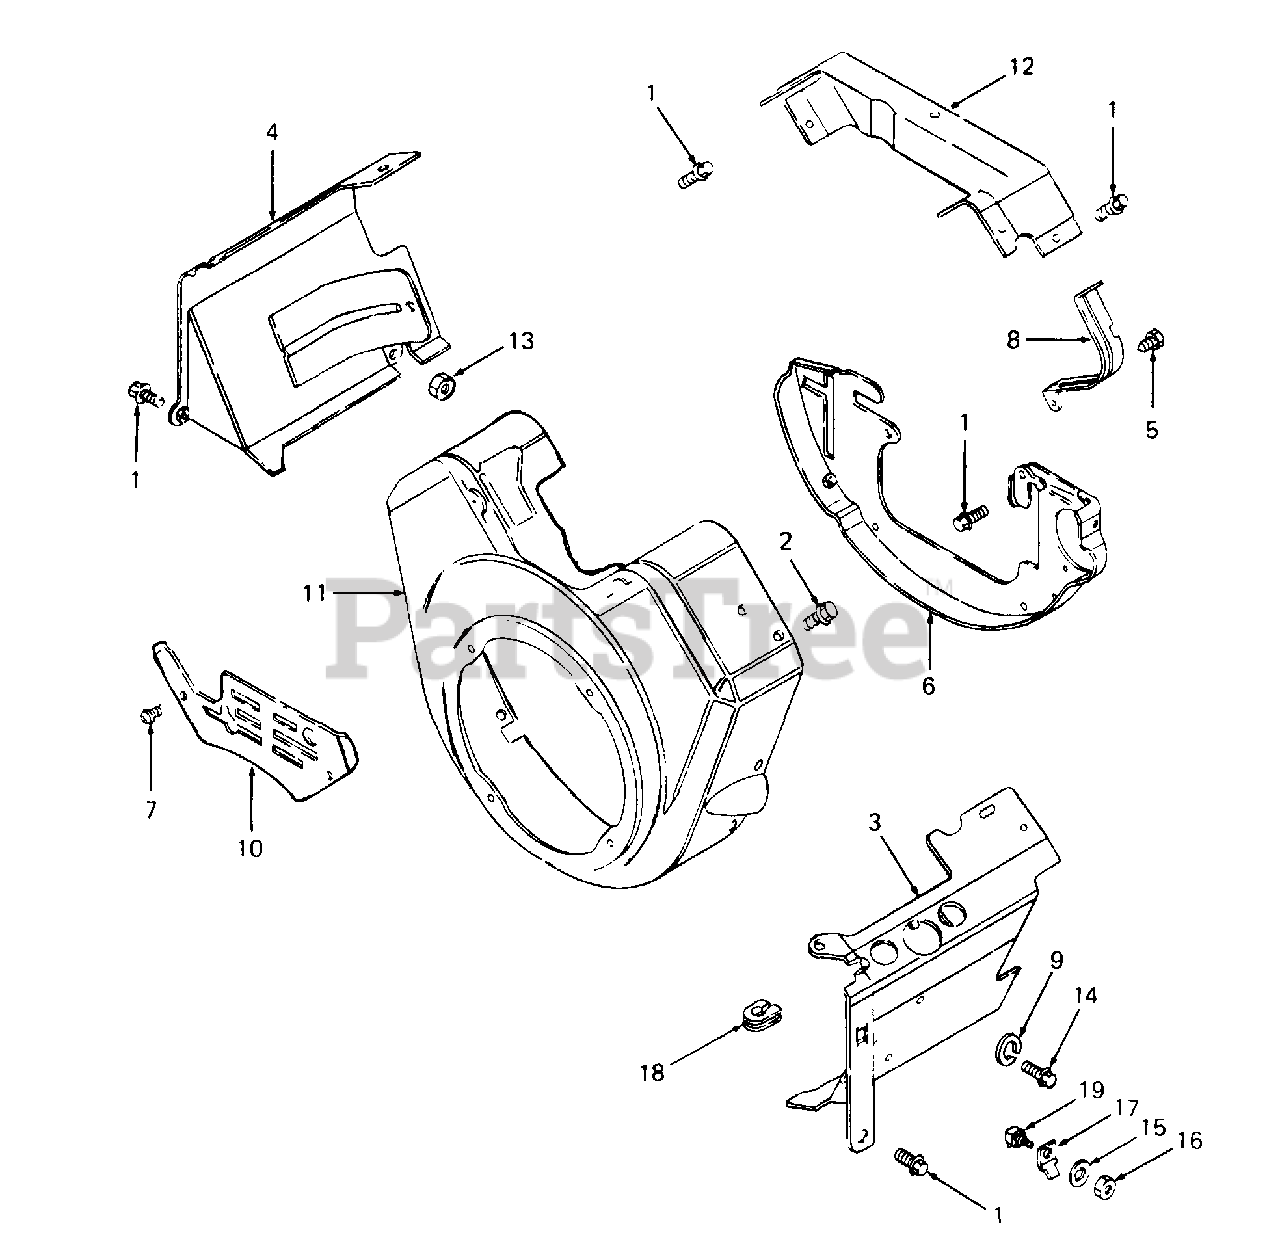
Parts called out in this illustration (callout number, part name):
1	Screw, Sems
2	Screw, Sems
3	Cover (Cylinder #1)
4	Cover (Cylinder #2)
5	Screw, Sems
6	Plate, Back
7	Screw, Sems
9	Washer, Lock
10	Cover, Carburetor
11	Housing, Blower
12	Cover, Valley Extension
13	Nut, Hex
14	Screw, Mtg
15	Washer, Lock, Internal Tooth
17	Terminal, Ground
18	Grommet, Cable
19	Insulator Assy
